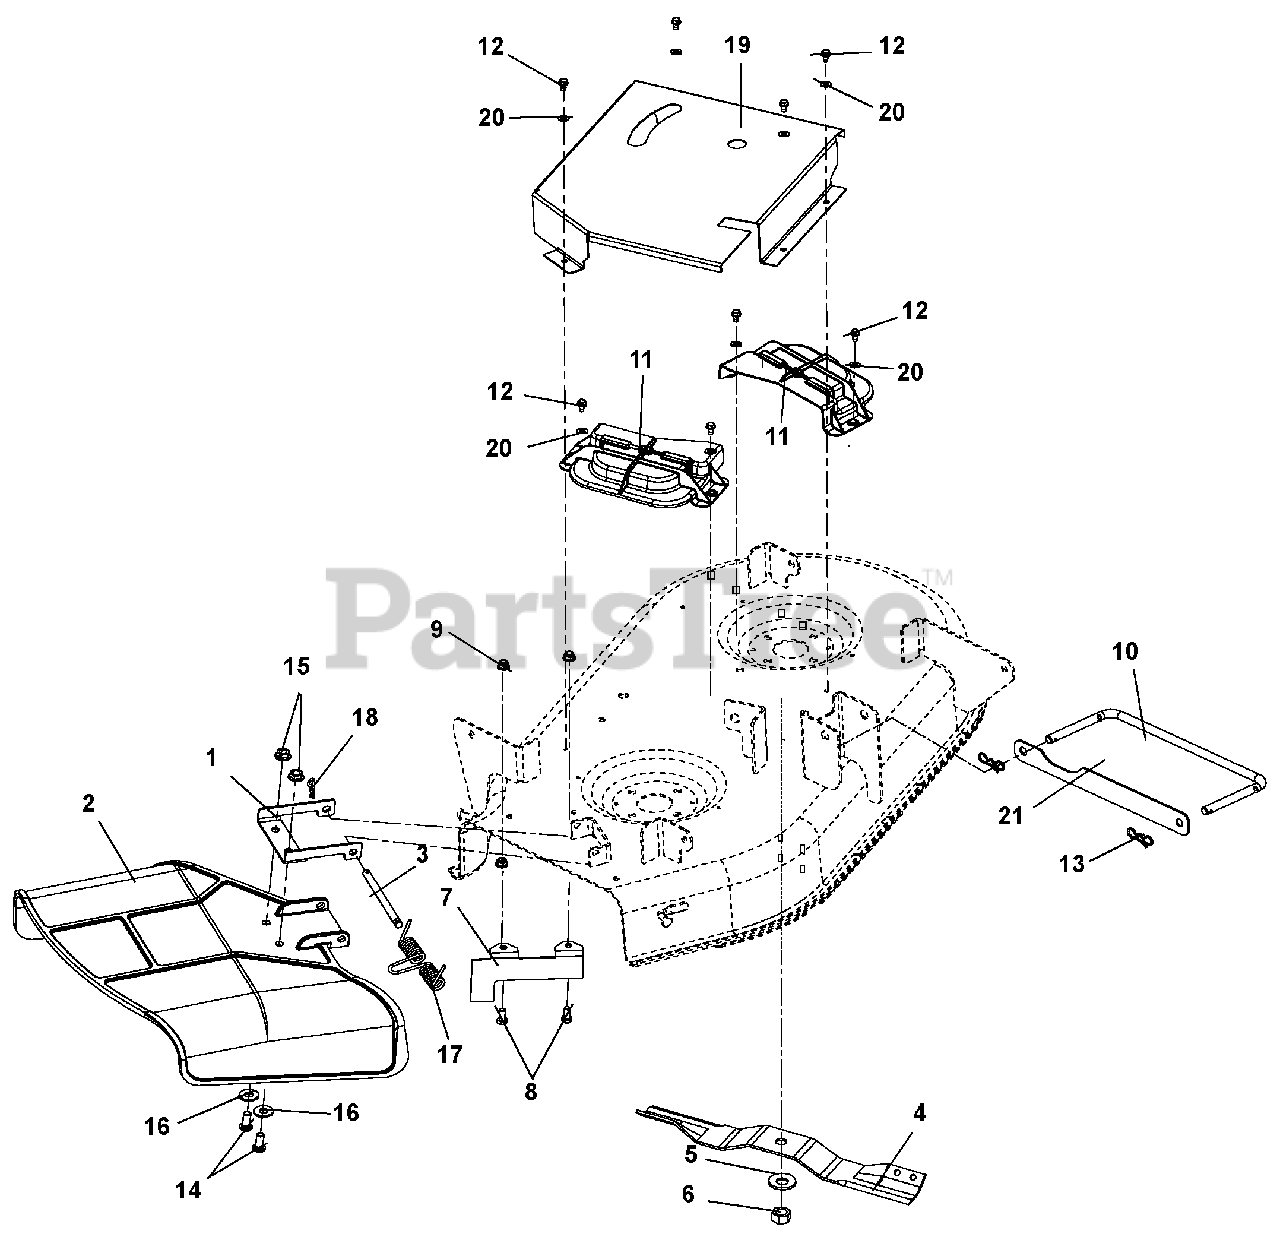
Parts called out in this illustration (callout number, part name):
1	CHUTE REINFORCEMENT
2	CHUTE, SIDE DISCHARGE
3	PIN, 5/16 X 3.88"
4	BLADE-17.34 OS MULCH
5	WSHR-BLVL .669X1.535X.138
6	NUT-HEX .62-18 YWZC
7	BRKT-BAFFLE, DISCHARGE 34"
8	@BLT-HEX .31-18X.75 GR5 YWZC
9	@NUT-LK-NYL-FLG .31-18 YWZC
10	WIREFORM, DRAG LINK
11	COVER-BELT, MOLDED
12	SCR-TAP .25-20X.50 LGHWH TR YZ
13	PIN,BOW TIE LOCKING .091X1.875
14	SCR-SKH .31-18X.75 BTNHD YWZC
15	@NUT-LK-TOP-FLG .31-18 YWZC
16	@WSHR-FL-STL.38X.875X.083 YWZC
17	SPRING, TORSION
18	PIN-HAIR INT .08X.18X1.18 YWZC
19	GUARD, 34" ZOOM/ZT CE BELT
20	NUT-PUSH .25X.50 O.D.
21	STRAP, DRAG LINK
